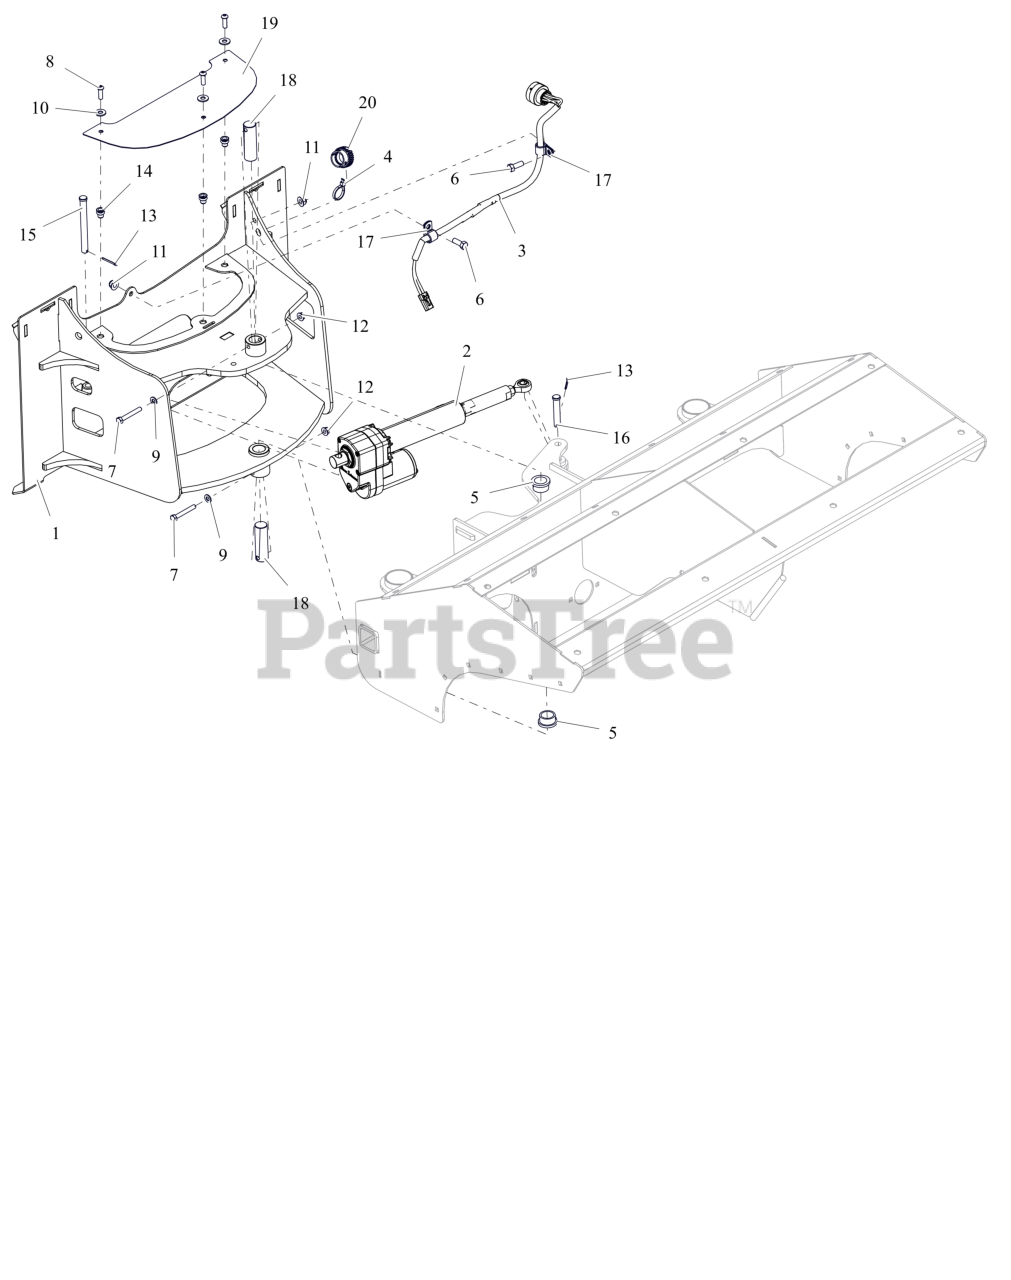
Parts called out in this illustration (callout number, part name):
1	WLDMT, BRUSH - W/DECAL
2	ACTUATOR, BRUSH
3	HARNESS, BRUSH
5	FLANGE, SLEEVE BEARING, OIL-EMBEDDED
6	BLT,HEX .38-16X1.00 G5 ZCC
7	BLT, HEX .31-18X2.25 G5 ZCC
8	BLT,SHCS-BTN .31-18X1.00 ZCC
9	WSHR,FLT .344X.688X.065 ZCC
10	WSHR,FLT .375X.875X.083 ZCC
11	NUT,NYL-FLG .38-16 GF ZCC
12	NUT,LK-NYL-FLG .31-18 G5ZC120
13	PIN,CTR.12X1.25EXTPRSQCT ZC120
14	RVT, HEX 5/16-18 SHORT
15	PIN, CLEVIS .50 X 4.75
16	PIN, CLEVIS .50 X 2.375
17	CLAMP, HARNESS - "P" (5/8" ID)
18	SHAFT, PIVOT
19	PLATE, COVER
20	CAP, CONNECTOR - AHDC04-18
